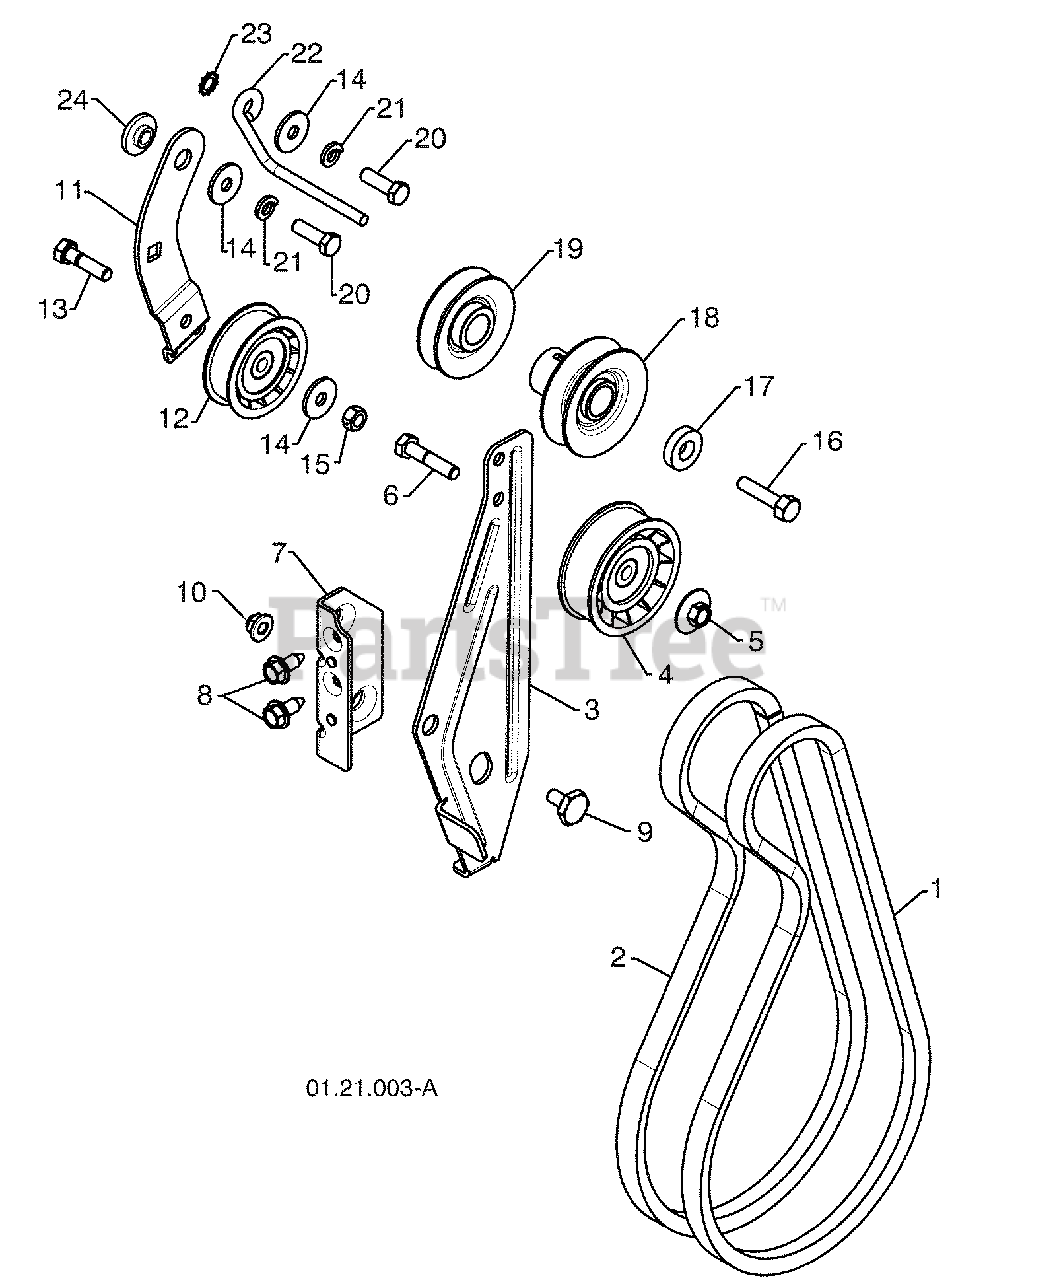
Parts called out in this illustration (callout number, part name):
1	IMPELLER BELT
2	TRACTION BELT
3	IDLER ARM BRACKET
4	IDLER PULLEY
5	NUT 5/16-18
6	SCREW 5/16-18 X 1 .50
7	IDLER BRACKET
8	SCREW 5/16-18 X .625
9	SHOULDER BOLT 5/16-18 X .500
10	NUT 5/16-18 NYLOCK
11	TRACTION IDLER ARM
12	TRACTION PULLEY
13	SCREW 5/16-18 X 1 .00
15	NUT 5/16-18
16	SCREW 3/8-24 X 1.375
18	PULLEY ENG IMPELLER
19	PULLEY ENG TRACTION
20	SCREW 5/16-18 X 1 .00
21	LOCKWASHER 5/16
22	BELT GUIDE
23	LOCKWASHER 5/16
24	IDLER BUSHING
